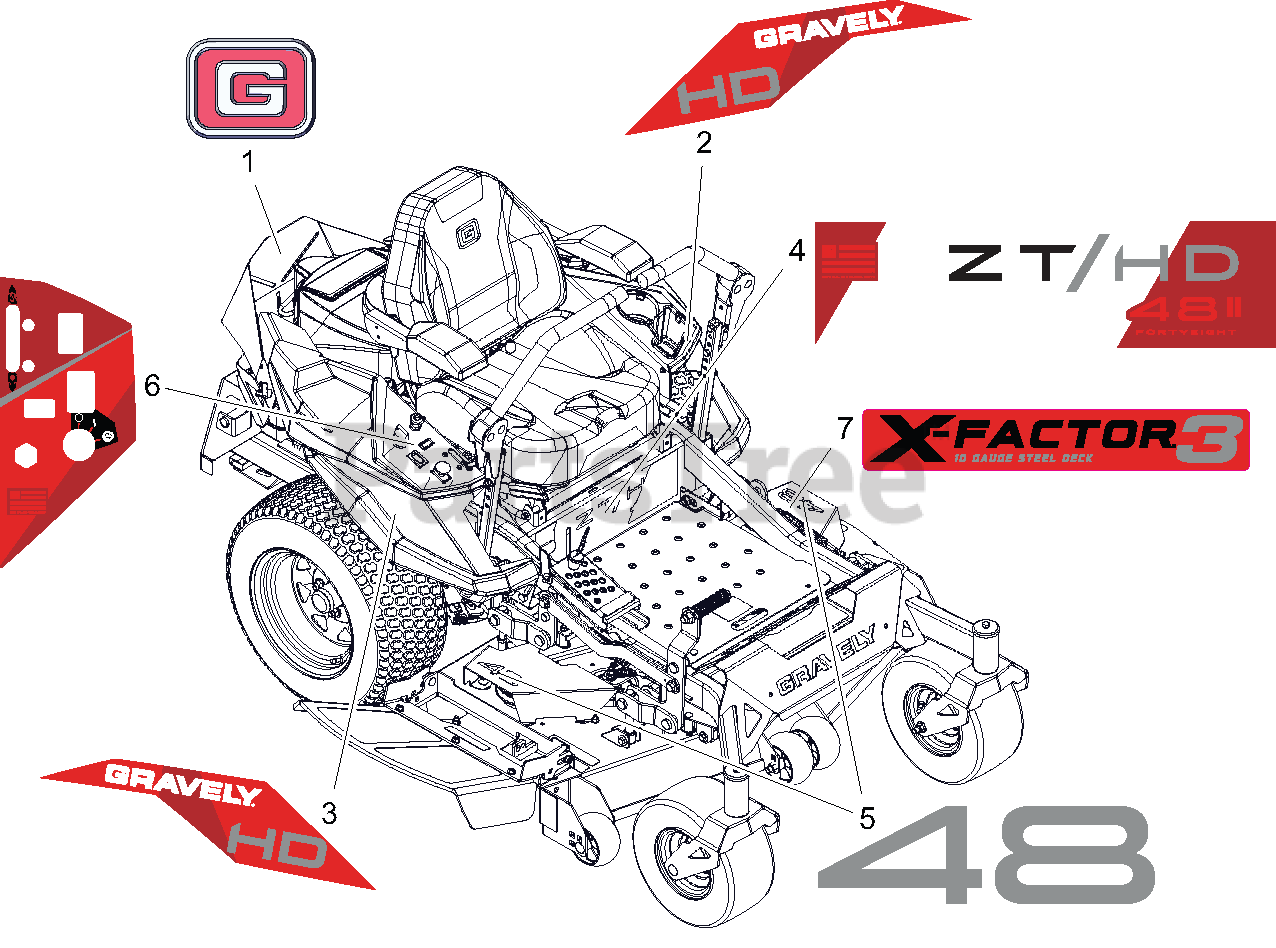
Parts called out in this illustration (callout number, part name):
1	DECAL, GRAVELY BRAND
2	DECAL, FENDER LH - HD
3	DECAL, FENDER RH - HD
4	DECAL, ZT/HD - 48
5	DECAL, DECK - 48
6	DECAL, CONTROL PANEL
7	DECAL, X-FACTOR 3
